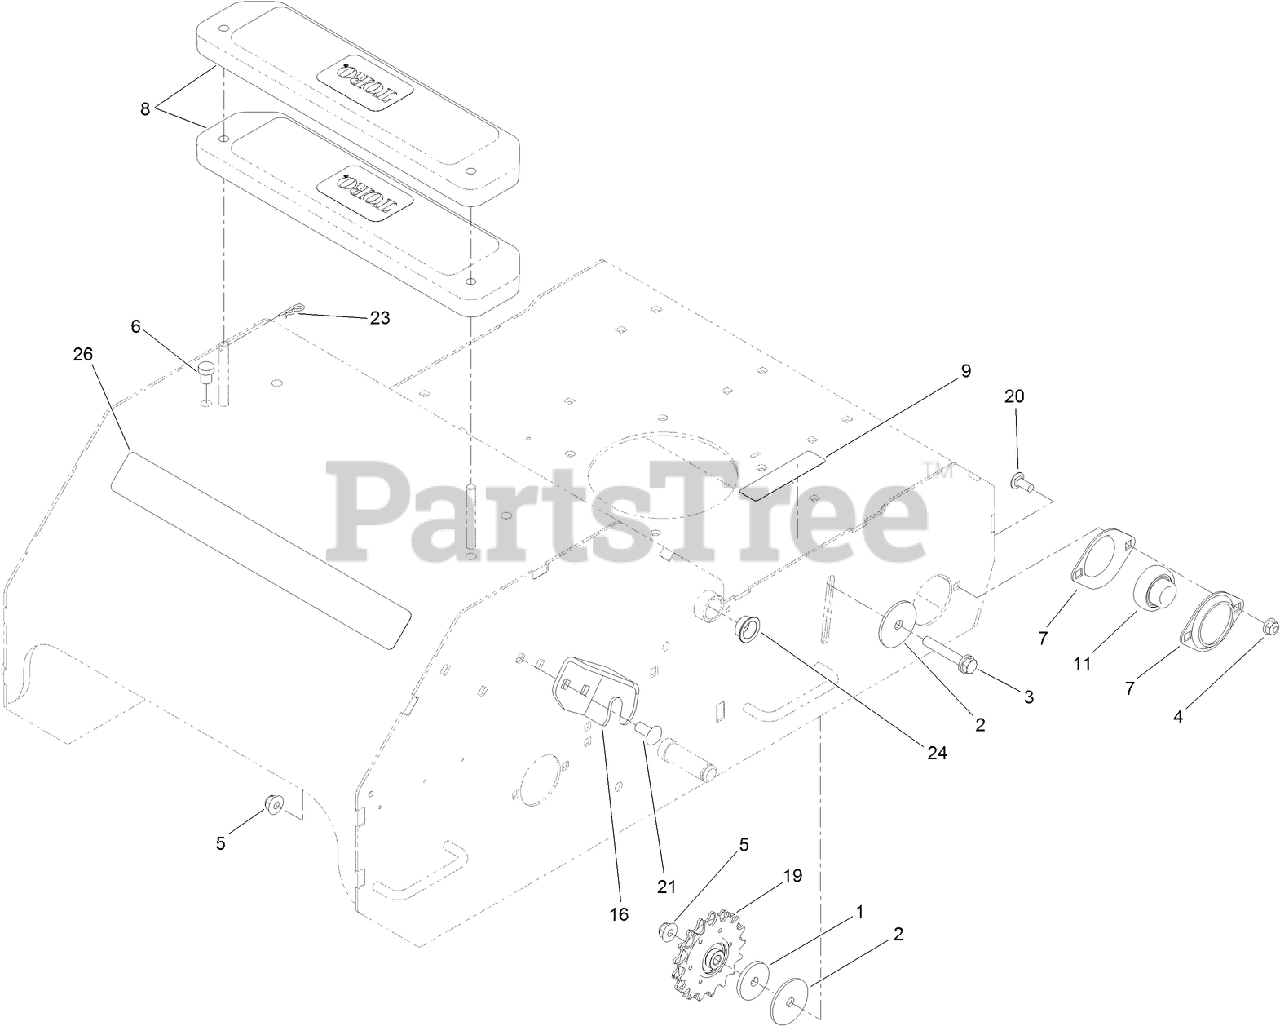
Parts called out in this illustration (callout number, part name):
1	WASHER
2	WASHER-FLAT
3	SCREW-HHF
4	NUT-HF, NI
5	NUT-HF, NI
6	BUMPER-RUBBER
7	FLANGE-BEARING
8	WEIGHT-CAST
9	DECAL-ARRESTER, SPARK
11	BEARING-RACE, EXTENDED
16	BRACKET-CABLE
19	SPROCKET-IDLER
20	SCREW-CARR
21	SCREW-CARR
23	PIN-COTTER
24	BUSHING-BRONZE
26	DECAL-OPERATION
